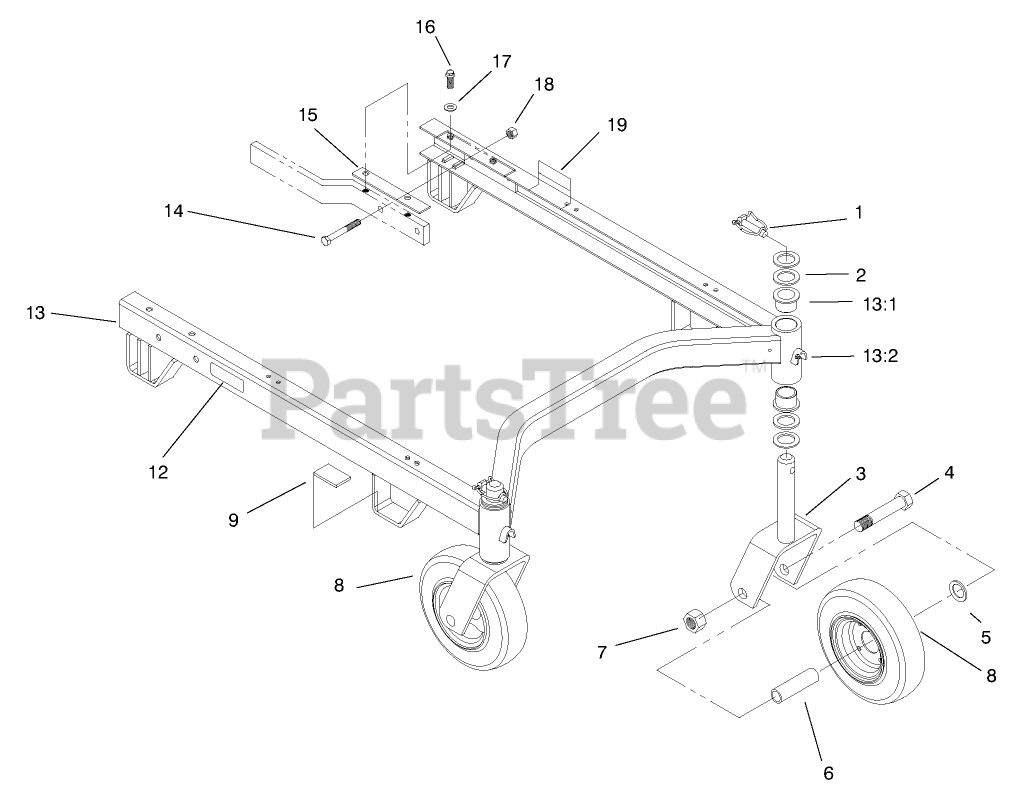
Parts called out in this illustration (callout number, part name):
1	PIN-LYNCH
2	WASHER-THRUST
3	Castor Fork
4	SCREW-HH
5	WASHER-FLAT
6	SPANNER-TIRE
7	NUT-HEX
8	TIRE AND BEARING ASM
9	CUSHION-RUBBER
12	DECAL-HOC, RH
13	SUSPENSION ASM
13:1	BUSHING
13:2	FITTING-GREASE
14	SCREW-HH
15	SHIM-CARRIER
16	SCREW-HHF
17	WASHER-FLAT
18	NUT-LOCK, SIDE
19	DECAL-HOC, LH
